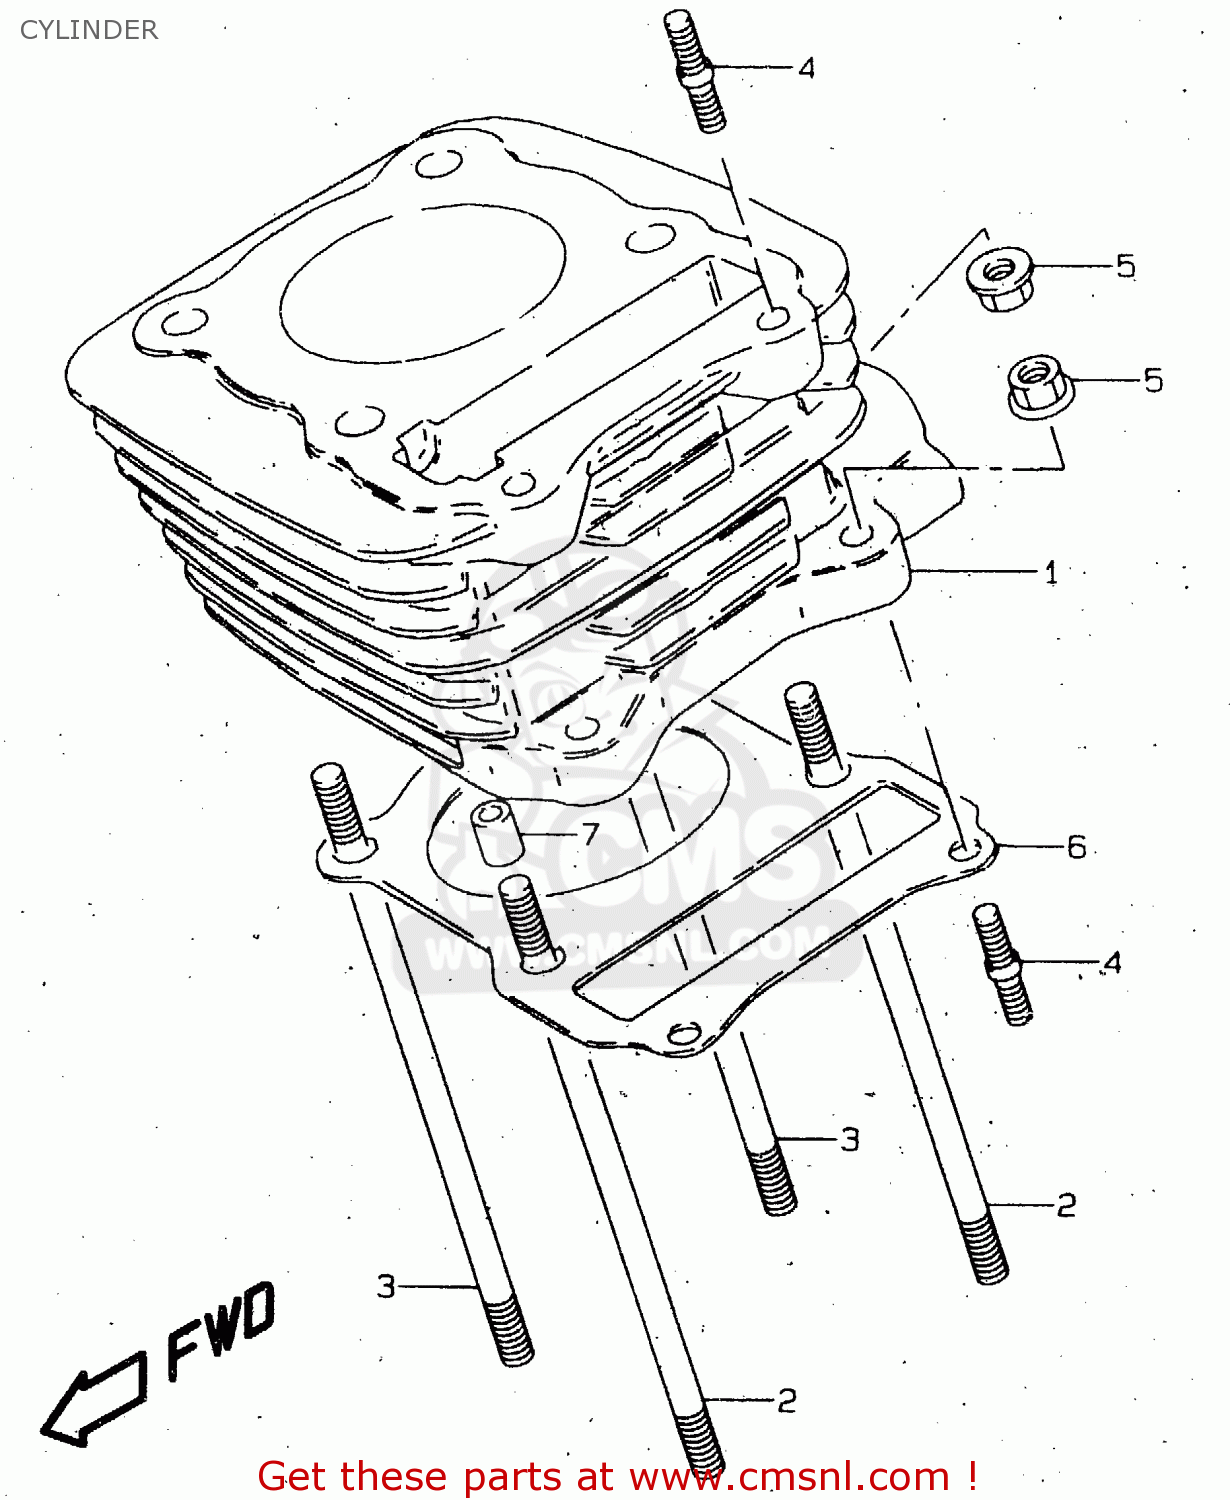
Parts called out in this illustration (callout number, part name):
1	CYLINDER
2	BOLT,STUD
3	BOLT,STUD
4	BOLT,STUD
5	NUT
6	GASKET,CYLINDER (NAS)
7	PIN
